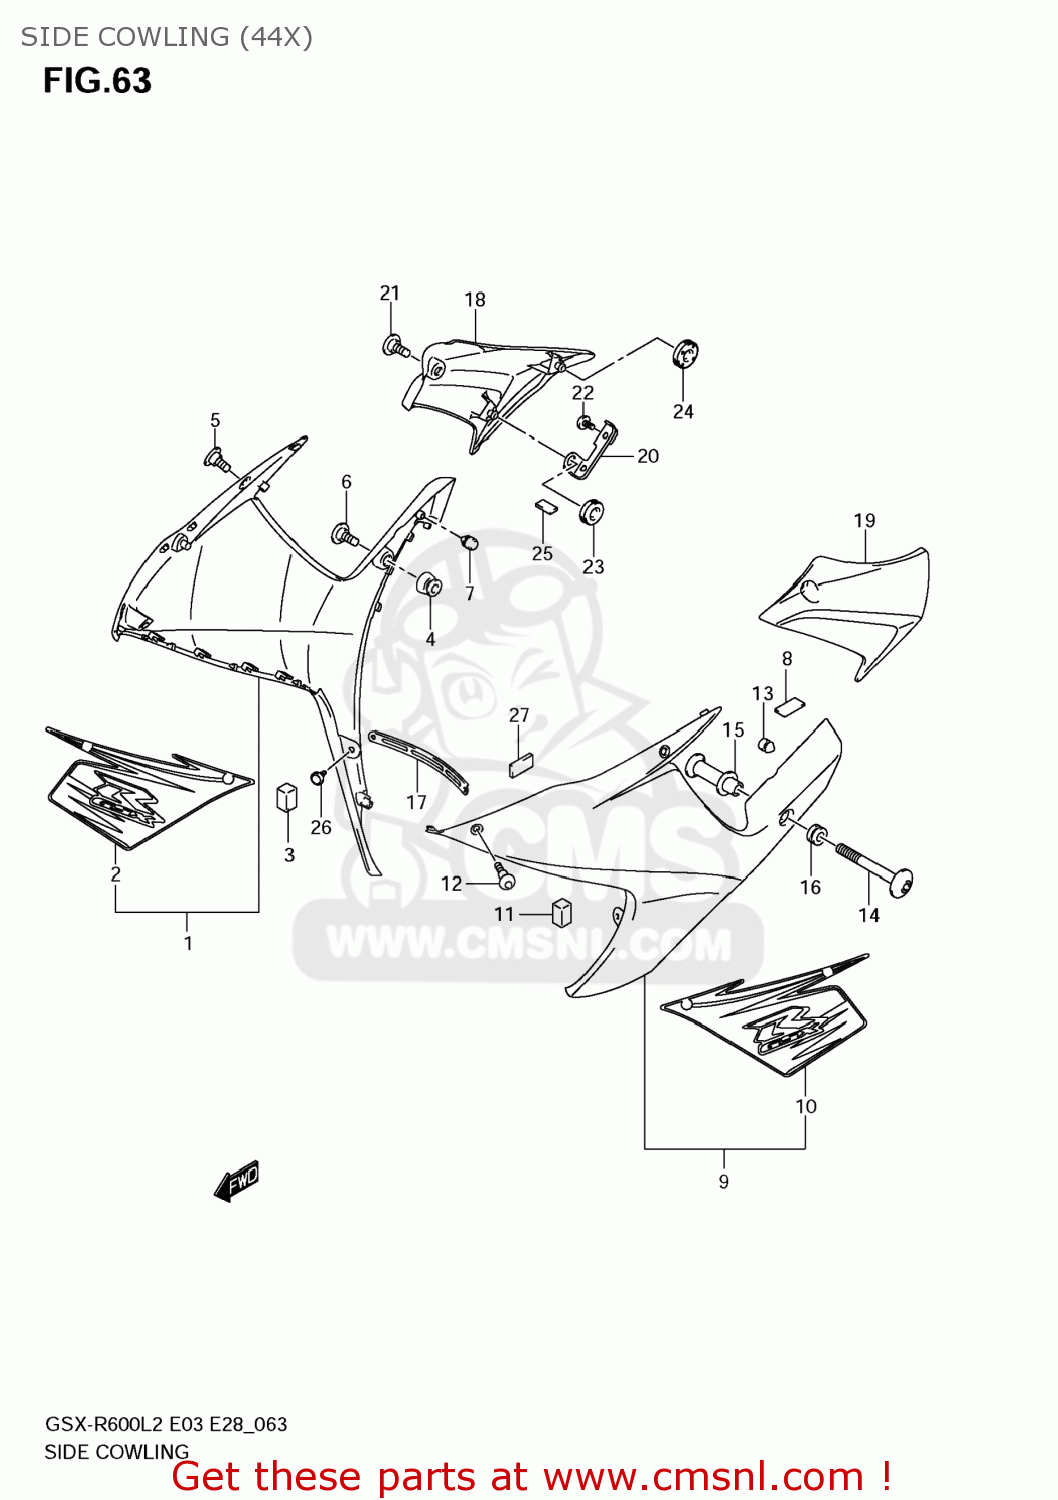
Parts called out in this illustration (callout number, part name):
1	COWLING,SIDE,R(BLACK)
2	TAPE,SIDE COWLING,R
3	CUSHION,SIDE COWL FR
4	CUSHION,UNDER COWLING,L
5	SCREW(5X13)
6	BOLT(6X20)
7	CUSHION
8	CUSHION,FUEL TANK NO.2
9	COWLING,SIDE,L(BLACK)
10	TAPE,SIDE COWLING,L
11	CUSHION,SIDE COWL FR
12	SCREW(5X13)
13	CUSHION
14	SCREW,SIDE COWL,L
15	SPACER,SIDE COWL,L
16	CUSHION
17	PLATE,UNDER COWL CTR
18	COVER,SIDE COWLING,R
19	COVER,SIDE COWLING,L
20	BRACKET,COVER SIDE,R
21	SCREW(5X13)
22	SCREW(6X12)
23	CUSHION
24	CUSHION
25	CUSHION
26	CLIP
27	PROTECTOR(30X80X1)
